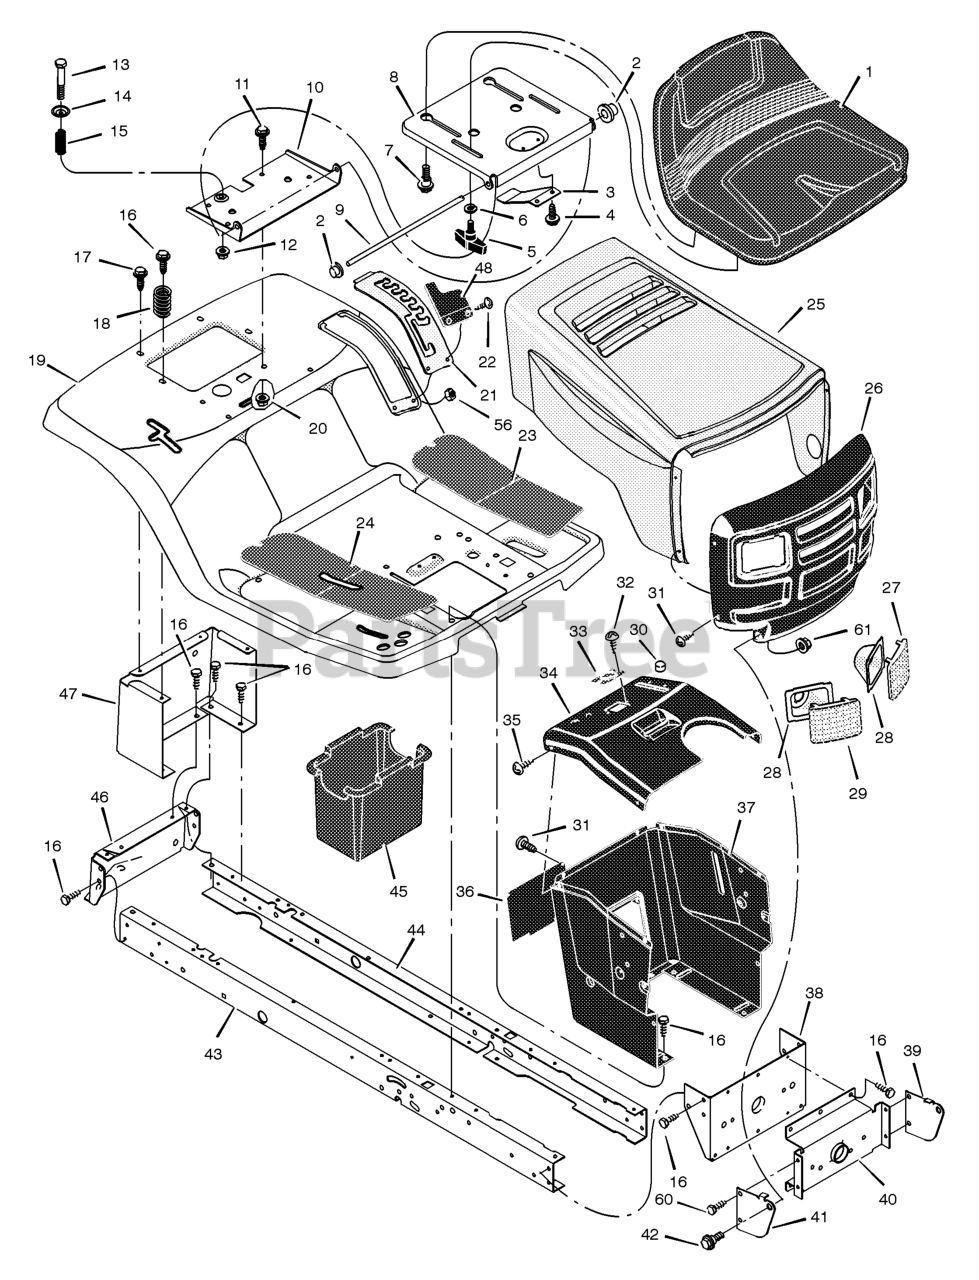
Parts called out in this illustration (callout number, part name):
1	Seat
2	Cap, Push On
5	Bolt, Wing
6	Washer
7	Bolt, Shoulder
8	Support, Seat
9	Rod, Pivot
10	Bracket, Pivot
11	Bolt
13	Bolt, Shoulder
15	Spring
19	Deck, Seat
20	Nut
21	Plate, Index
23	Mat, Left
24	Mat, Right
27	Lens, Left
28	Reflector, Headlight
29	Lens, Right
30	Bumper
31	Screw
33	Bearing, Steering
36	Panel, Access
37	Support, Dash
38	Bracket, Rear Hanger
39	Support, Left Grille
40	Axle, Hanger
41	Support, Right Grille
42	Bolt, Shoulder
43	Frame, Right
44	Frame, Left
45	Container, Battery
46	Plate, Hitch
47	Panel, Rear
48	Cover, Detent
56	Locknut
61	Locknut
